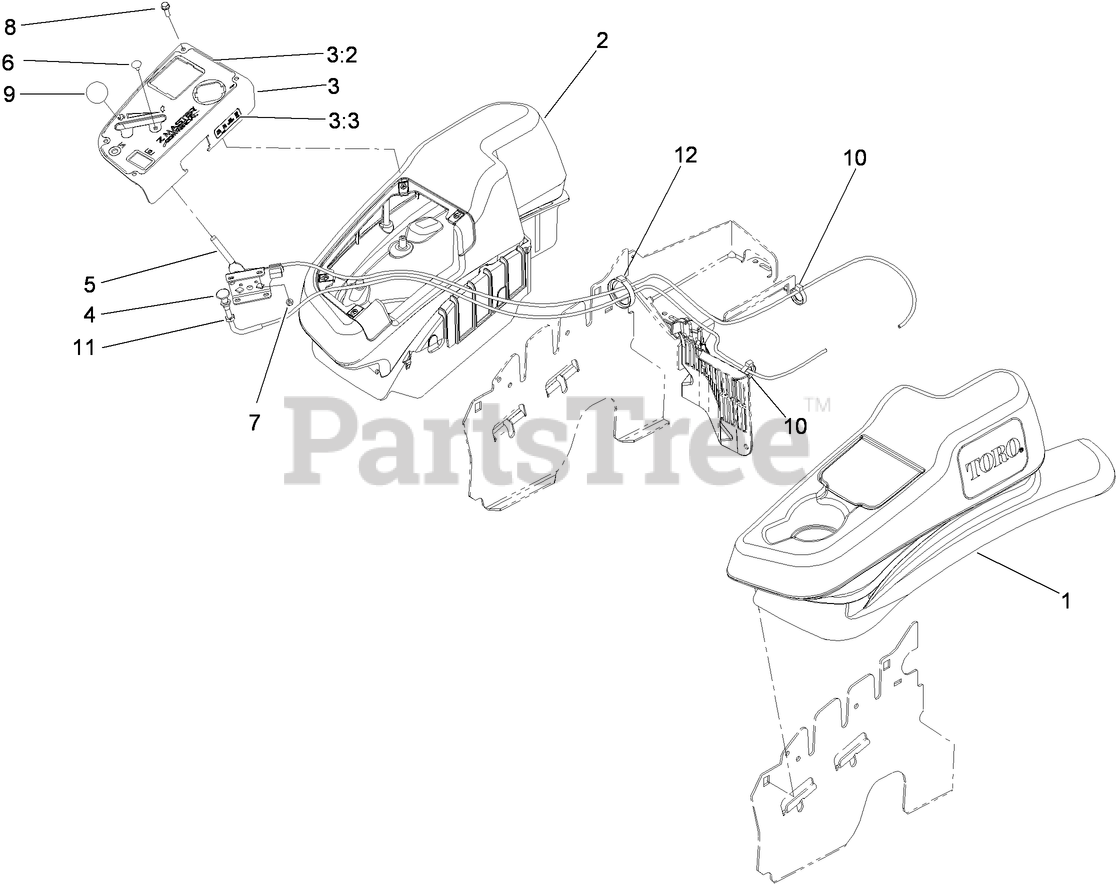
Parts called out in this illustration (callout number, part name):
1	LH NARROW FENDER/CONSOLE ASM
2	RH NARROW FENDER/CONSOLE ASM
3	CONTROL PANEL ASM
3:2	DECAL-PANEL, CONTROL
3:3	DECAL-FUSES
4	CHOKE CONTROL ASM
5	THROTTLE CONTROL ASM
6	BOLT-CARR
7	NUT-LOCK, NI
8	SCREW-HWH
9	KNOB-BALL
10	CLAMP-HOSE
11	NUT-HJ
12	CLAMP-HARNESS
